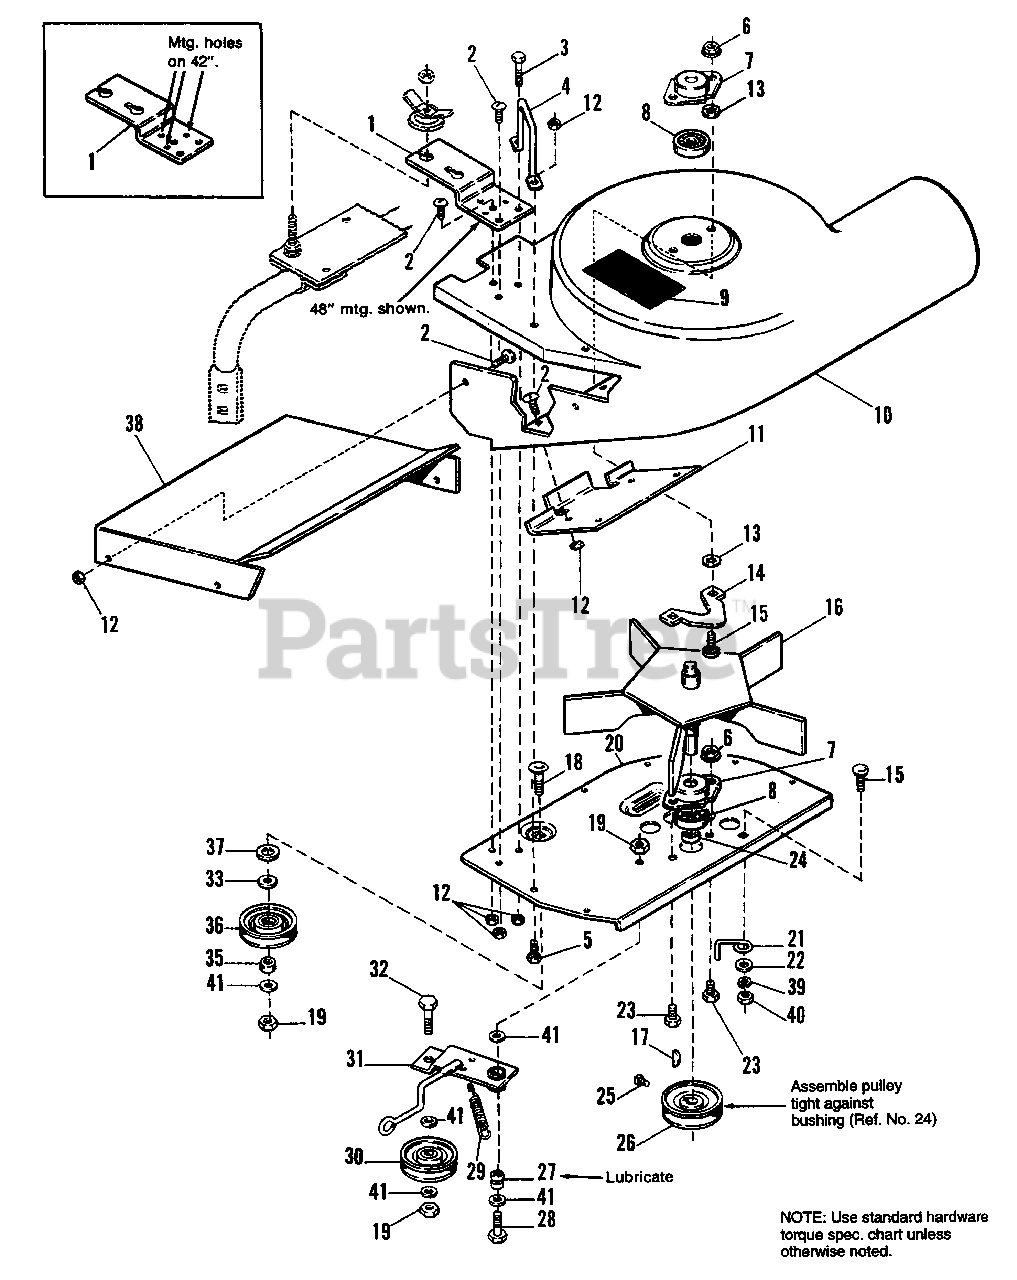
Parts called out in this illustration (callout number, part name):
1	MOUNTING PLATE
2	CAPSCREW, Hex Hd., 1/4-20 x 5/8
3	CAPSCREW, Hex, 1/4-20 x 2-1/4
4	STOP, Deflector
5	CAPSCREW, Hex, 1/4-20 x 7/8
6	NUT, Range, Lock, 5/16-18
7	BEARING, Retainer
9	DECAL, Warning
10	HOUSING, Blower
11	HOOK, Stoneguard
12	NUT, Hex Range Whizlock, 1/4-20
13	PUSH NUT, Nylon, 1/4-20
14	PLATE, Range
15	CARRIAGE BOLT, 5/16-18 x 3/4
16	FAN ASSY. (5 Blade)
17	KEY, Woodruff
18	CARRIAGE BOLT, 3/8-16 x 1-1/4
19	NUT, Hex Jam Lock, 3/8-16
20	PLATE, Shroud
22	WASHER, Plain, 11/32
23	CAPSCREW, Thin Hd., 5/16-18 x 3/4
25	SETSCREW, Socket Hd., 5/16-18 x 3/8
26	PULLEY, Driven
27	SPACER
28	CAPSCREW, Hex Hd., 3/8-16 x 1/2
29	SPRING, Tension
30	PULLEY, Idler, Adjustable
31	IDLER ARM ASSY.
32	CAPSCREW, 3/8-16 x 1
33	WASHER, Special
34	SCREW, Truss Hd., 1/4-20 x 3/4
36	PULLEY, Idler, Fixed
37	WASHER, Plain, 1/2
38	COVER, Top
39	WASHER, Spring
40	NUT, Hex, 5/16
41	WASHER, 13/32
